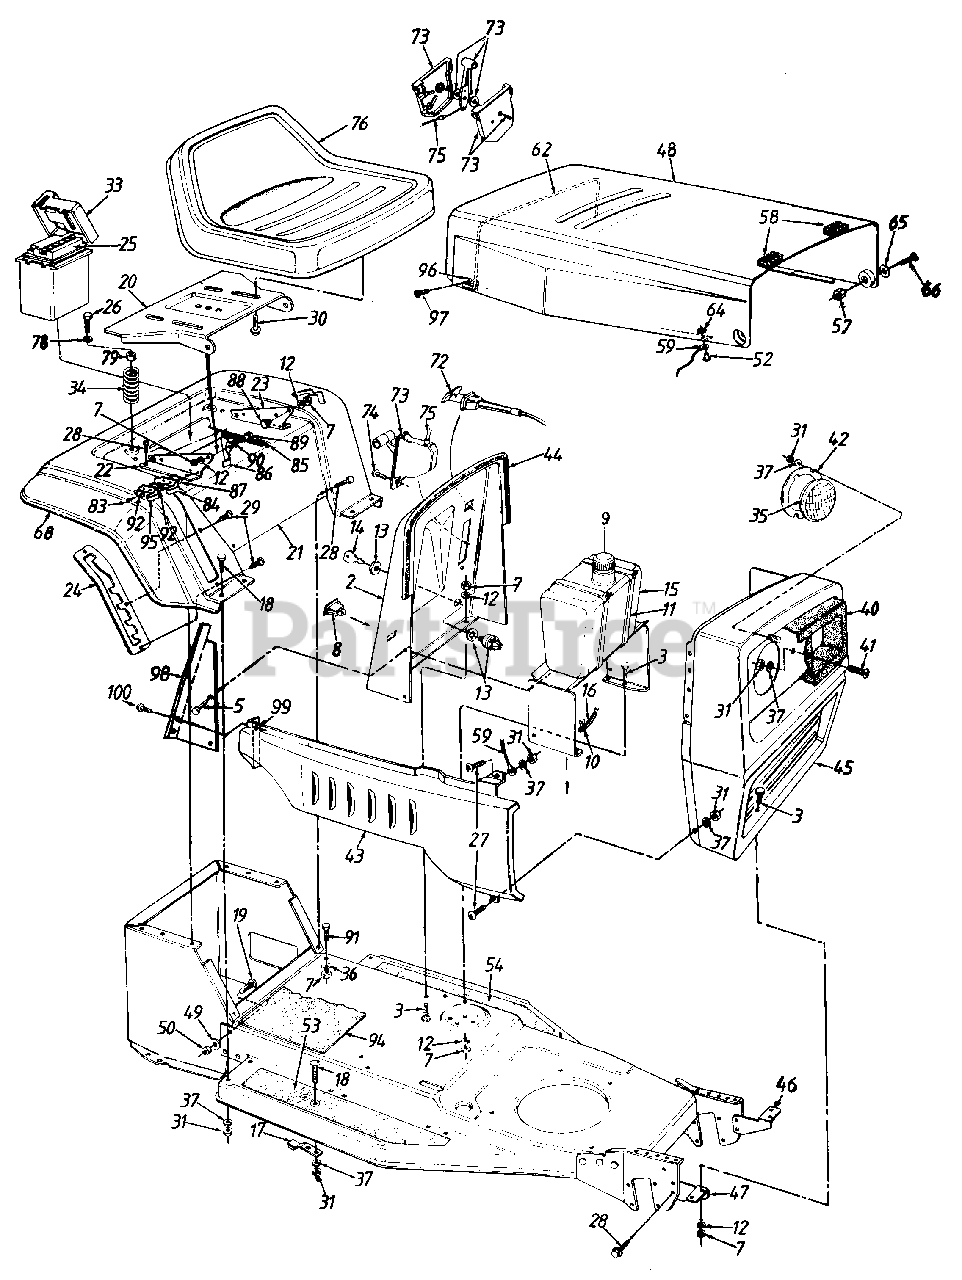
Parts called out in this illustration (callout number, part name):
1	Dash Panel Support Brkt.
5	Hex AB-Tap Scr. 1/4 x .62"
7	Hex Nut 5/16-18 Thd.
8	Light Switch
9	Gas Cap
11	Cable Tie
12	L-Wash. 5/16" l.D.
13	Ignition Switch
14	Ignition Key
15	Fuel Tank
16	Gas Line-15" Lg.
17	Blade Brake Ass'y.
18	Carriage Bolt 1/4-20 x .62"
19	Ribbed Neck Bolt 3/8-24 x .8n
20	Seat Pivot Brkt.
25	Battery
26	Hex Self-Tap Screw 5/6-18 x 1.25" Lg.
27	Truss Mach. Scr. 1/4-20 x .5" Lg
28	Hex AB-Tap Scr. 5/16 x .75" Lg
29	Torx Mach. AB-Tap Scr. 1/4 x .62" Lg.
30	Hex Self-Tap Scr. 3/8-16 x .75" Lg.
31	Hex Nut 1/4-20 Thd.
33	Battery Box w/Cover
34	Compression Spring
35	Headlight
36	Bell-Wash. 6/16" l.D.
37	L-Wash. 1/4" l.D.
41	C-Sunk Mach. Scr. 1/4-20 x 1.5"
42	Headlight Retainer
43	Side Panel-R.H.
44	Trim Strip 31" Lg.
47	Grille Mtg. Brkt.-R.H.
50	Hex L-Nut 3/8-24 Thd.
52	Truss Mach. Scr. #10-24 x .5" Lg.
53	Foot Pad-R.H.
54	Foot Pad-L.H.
57	Lock Nut 1/4-28 Thd.
64	Hex Sems Nut #10-24 Thd.
65	Spr. Wash. .39" l.D. x .62" O.D.
66	Shld. Bolt
68	Trim Strip 81" Lg.
72	Choke Control
73	Throttle Control Box
74	Truss AB-Tap Scr. #10 x .5"
75	Throttle Wire
76	Seat Assembly
78	Flat Wash. .344" I.D. x .88" O.D.
83	Hex Tap Scr. #8 x .5" Lg.
84	Safety Switch
85	Ext. Spring 5.3ln Lg.
86	Seat Lift Brkt.
87	Insulator Boss Plate
88	Shld. Bolt .437" Dia. x .162" Lg.
89	Shld. Bolt .437" Dia. x .268" Lg.
90	Spr. Wash. .445" I.D. x .75" O.D.
91	Hex Wash. Hd. Scr. 5/16-18 x .62" Lg.
92	Insulator Plate
94	Center Foot Pad
95	Safety Switch
96	Hood Spring Retainer
97	Oval Hd. Self-Tap Scr. .5" Lg.
98	Side Panel Mtg. Brkt.-R.H.
99	Speed Nut #10-24 Thd.
100	Truss Mach. B-Tap Scr. #10 x .5" Lg.
